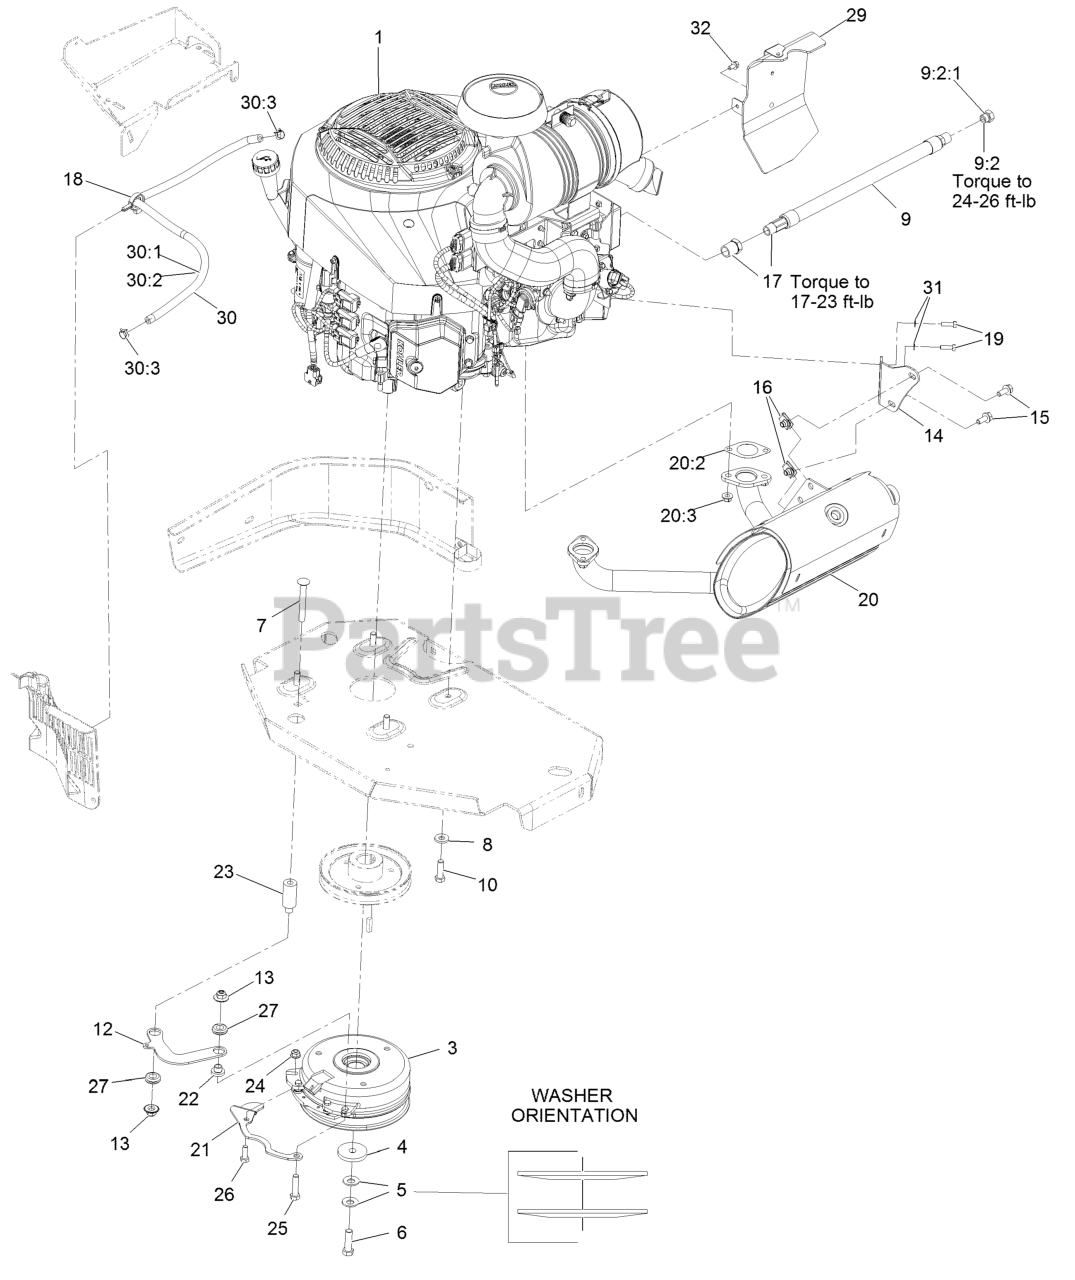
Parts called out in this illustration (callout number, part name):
1	Engine-Koh Ecv980 Efi-Egov
4	WASHER-CLUTCH
5	WASHER-SPRING
6	SCREW-HH 7/16-20 X 1 1/2 W/LOCTITE
7	SCREW-CARR
8	WASHER-BELLEVILLE
9	OIL DRAIN HOSE ASM
9:2	PLUG-HH
9:2:1	O-RING
10	SCREW-HH
12	LINK-ANCHOR, CLUTCH
13	Nut-Nyloc 3/8-16 Flg
14	BRACKET-MUFFLER
15	SCREW-HHF
17	BUSHING
18	CLAMP-HOSE
19	SCREW-HH M6-1 X 20Mm W/Patch
20	MUFFLER-940-980 KOH EFI
20	MUFFLER KIT
20:2	GASKET-EXHAUST
20:3	NUT-FLANGE, LOCK
21	BELT-GUIDE
24	NUT-HF, NI
25	SCREW-HH
26	SCREW-HH
27	GROMMET-RUBBER
29	REAR BAFFLE ASM
30	FUEL LINE ASM
30:1	HOSE-FUEL
30:2	SLEEVE-THERMAL
30:3	CLAMP-HOSE
31	WASHER-SPRING
32	SCREW-HWH
